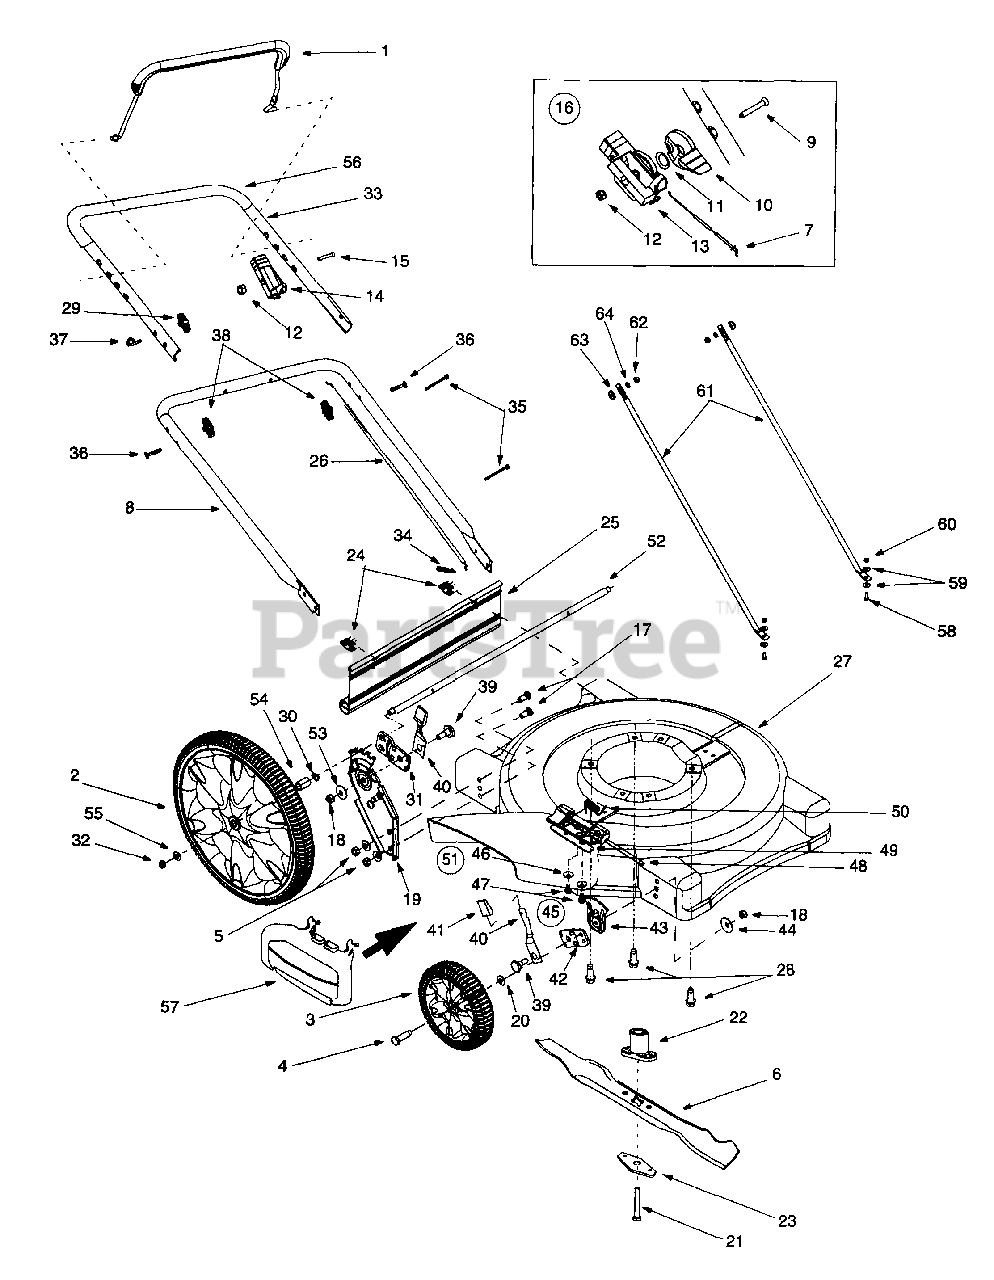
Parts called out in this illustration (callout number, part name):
2	Rear Wheel Assembly
3	Front Wheel w/o Bearing
4	Front Axle Bolt
5	Hex Nut 3/8-24 Thd.
6	Blade, 22"
7	Throttle Cable 51"
9	Oval C-Sunk Mach. Scr.
10	Throttle Lever
11	Spring Lever
12	Hex Lock Nut 1/4-20 Thd.
13	Throttle Body
14	Control Cable Housing
15	Screw, 1/4-20 x 1.3
16	Throttle Box Comp.
17	Ribbed Neck Bolt 3/8-24 x 80"
18	Hex Nut 3/8-16 Thd.
21	Hex Bolt 3/8-24 x 1.5"
22	Blade Adapter
23	Blade Bell Support
24	Hinge Clip
25	Rear Flap Ass'y.
26	Control Cable - 39"
29	Handle Knob 1/4-20 Thd.
30	Wave Washer
31	Pivot Bar - L.H.
32	Hex Jam Nut 3/8-16 Thd.
35	Cable Tie
36	Curved Hd. Bolt 5/16-18 x 2"
37	Rope Guide
38	Hand Knob
39	Shoulder Bolt
40	Spring Lever Assembly w/Knob
41	Knob only
42	Pivot Bar
43	Height Adj. Plate
44	Bell Washer
45	Front Height Adjustment Assembly Comp. - R.H.
46	Bell Washer
47	Hex Head Tap Screw, 1/4-20 x .5"
48	Hinge Pin
49	Adapter Plate
50	Torsion Spring
51	Chute Deflector Ass'y.
52	Rear Axle
53	Bell Washer
54	Spacer
55	Flat Washer
56	Foam Grip
57	Mulching Baffle
58	Hex Bolt 1/4-20 x .620 Gr.5
59	Bell Washer
60	Hex Nut 1/4-20
63	Saddle Washer
64	Lock Washer
